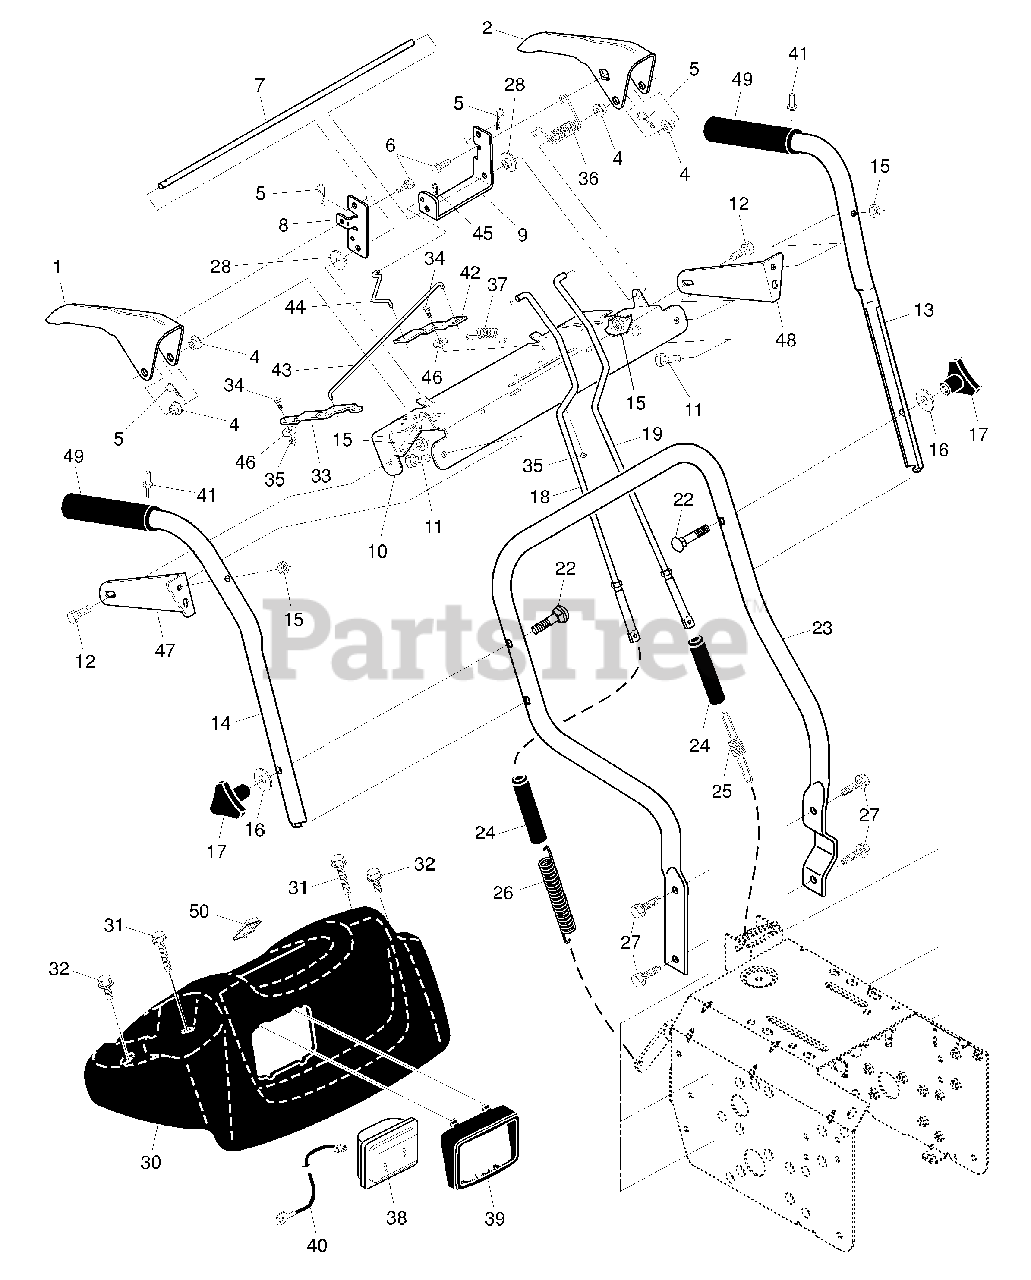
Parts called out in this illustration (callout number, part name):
1	Lever, Auger Control, RH
2	Lever, Traction Drive Control, LH
4	Bushing, Flange
5	Retainer, Hairpin
6	Screw, Hex Head
7	Rod, Interlock
8	Arm, Impeller Rod
9	Arm, Traction Rod
10	Panel, Control
11	Screw, Hex Head 5/16-18 x 1-1/2
12	Screw, Hex Head 5/16-18 x 1-3/4
13	Handle Tube, LH
14	Handle Tube, RH
15	Nut, Lock 5/16-18
16	Washer, Flat 3/8
17	Knob, Handle
18	Rod, Auger Control
19	Rod, Traction Control
20	End, Control Rod
21	Nut, Hex, Jam 5/16-18
22	Bolt, Carriage 3/8-16 x 2-1/4
23	Handle Tube, Lower
24	Sleeve, Spring
25	Spring, Traction Drive
26	Spring, Auger Control
27	Screw, Hex Head 3/8-16 x 1
30	Console, Panel
31	Screw, Hex Head, Tapping #10-24 x 1-1/4
32	Screw, Hex Head, Tapping #10-24 x 1/2
33	Latch, Interlock
34	Bolt, Shoulder
35	Nut, Lock 1/4-20
36	Spring, Torsion
37	Spring, Interlock
38	Headlight, Halogen
38	Bulb, Halogen
39	Bezel, Headlight
40	Harness, Headlight
42	Lever, Interlock
43	Rod, Latch, Interlock
44	Rod, Arm, Interlock
46	Washer, Friction
47	Mounting Bracket, Handle, RH
48	Mounting Bracket, Handle, LH
49	Grip, Handle, Heated
50	Switch, Heated Handle Grips
